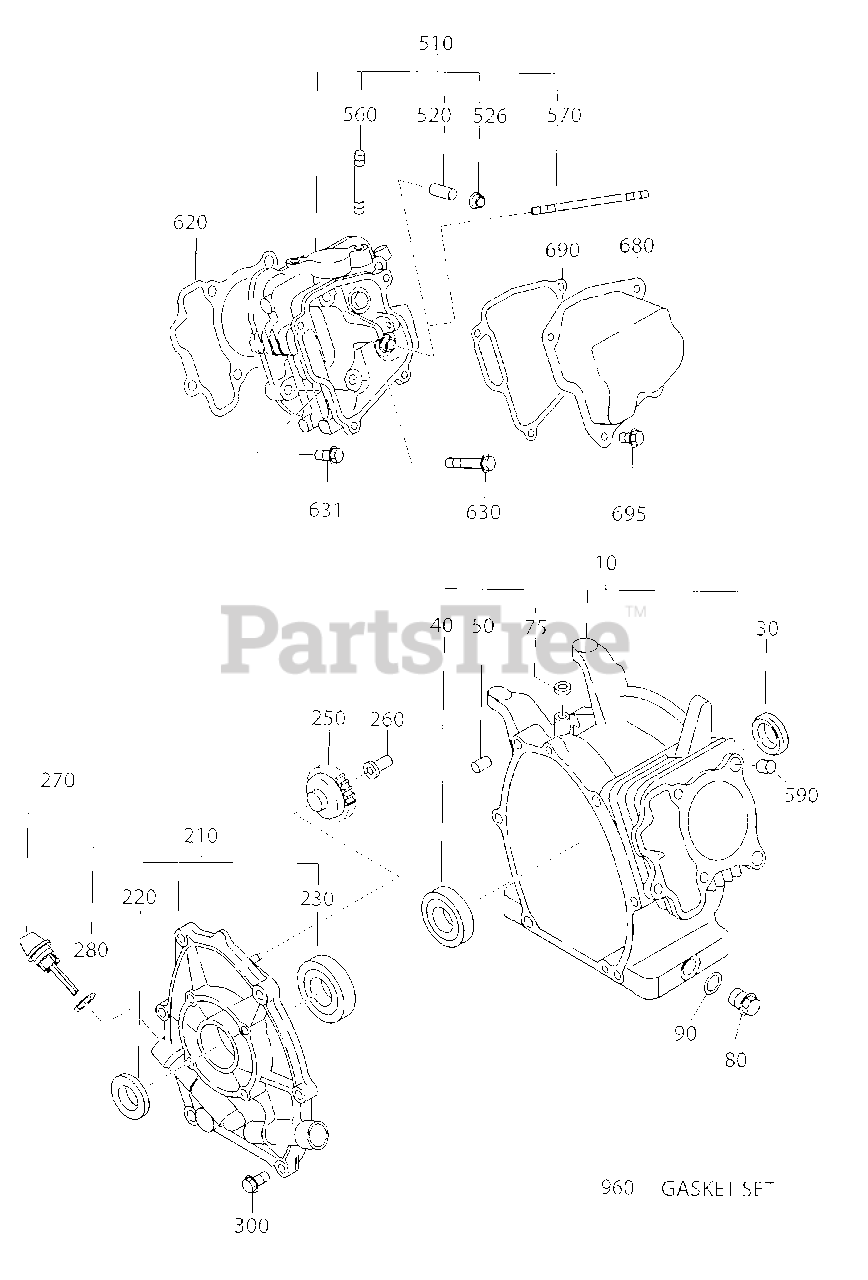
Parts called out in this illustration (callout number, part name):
210	MAIN BEARING COVER CP
250	GOVERNOR GEAR CP
260	GOVERNOR SLEEVE
510	CYLINDER HEAD CP
680	ROCKER COVER CP
690	GASKET, ROCKER COVER
